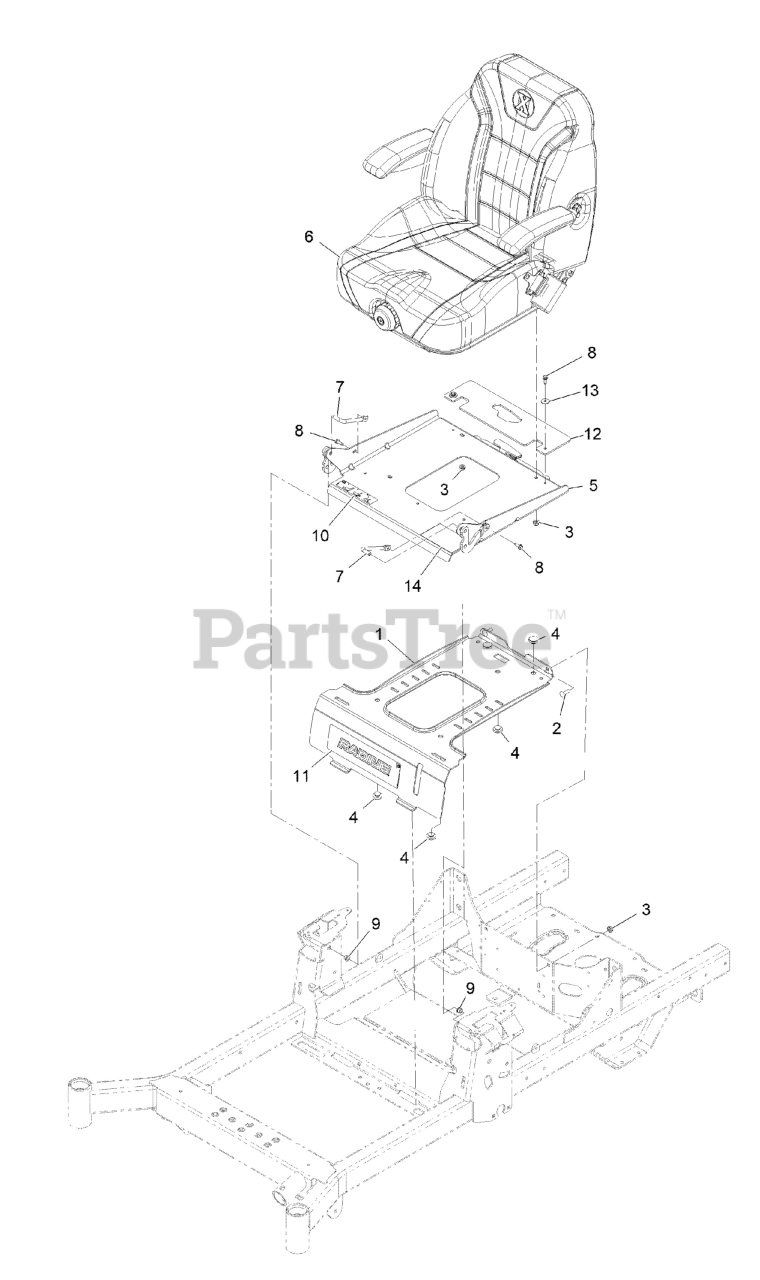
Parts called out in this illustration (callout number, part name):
1	PLATE-RETAINER, TANK
2	SCREW-CARR
3	NUT-HF, NI
4	BUMPER-SEAT
5	SEAT PAN AND LATCH ASM
6	Seat, Susp.
7	PIN-PIVOT, SEAT
8	SCREW-HWH, THREAD ROLL
9	BUSHING-FLANGED
10	DECAL-LATCH, SEAT
11	DECAL-RADIUS LOGO
12	GUARD-SEAT, RUBBER
14	DECAL-SERVICE AID
